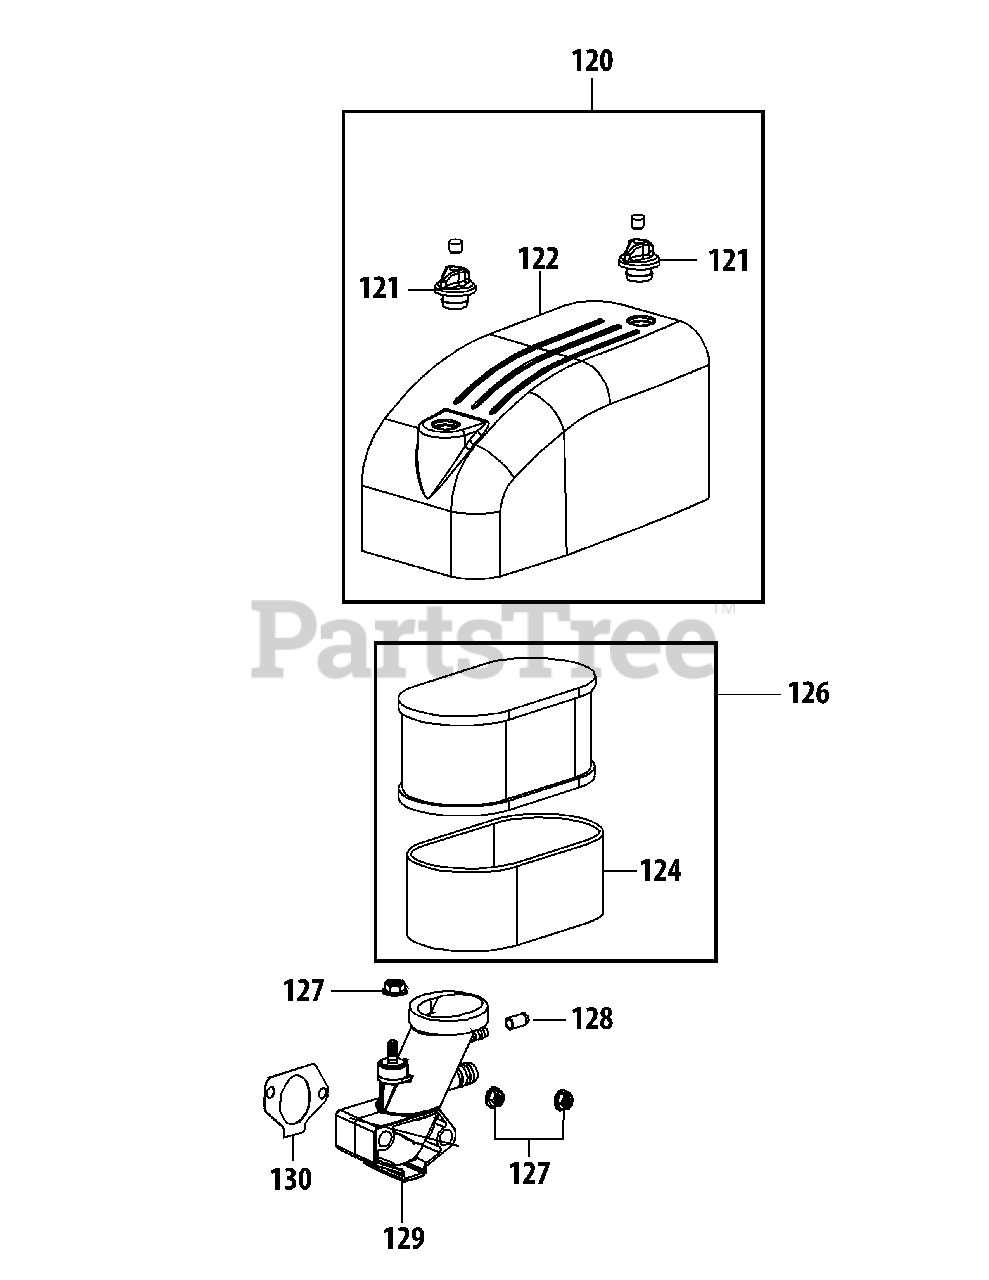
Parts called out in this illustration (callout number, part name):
120	Air Filter Cover Assembly
121	Air Filter Lock Nut
122	Air Filter Cover
124	Sponge Filter
126	Air Filter & Sponge Assembly
127	Nut M6
128	Rubber Cap
129	Manifold
130	Manifold Gasket
